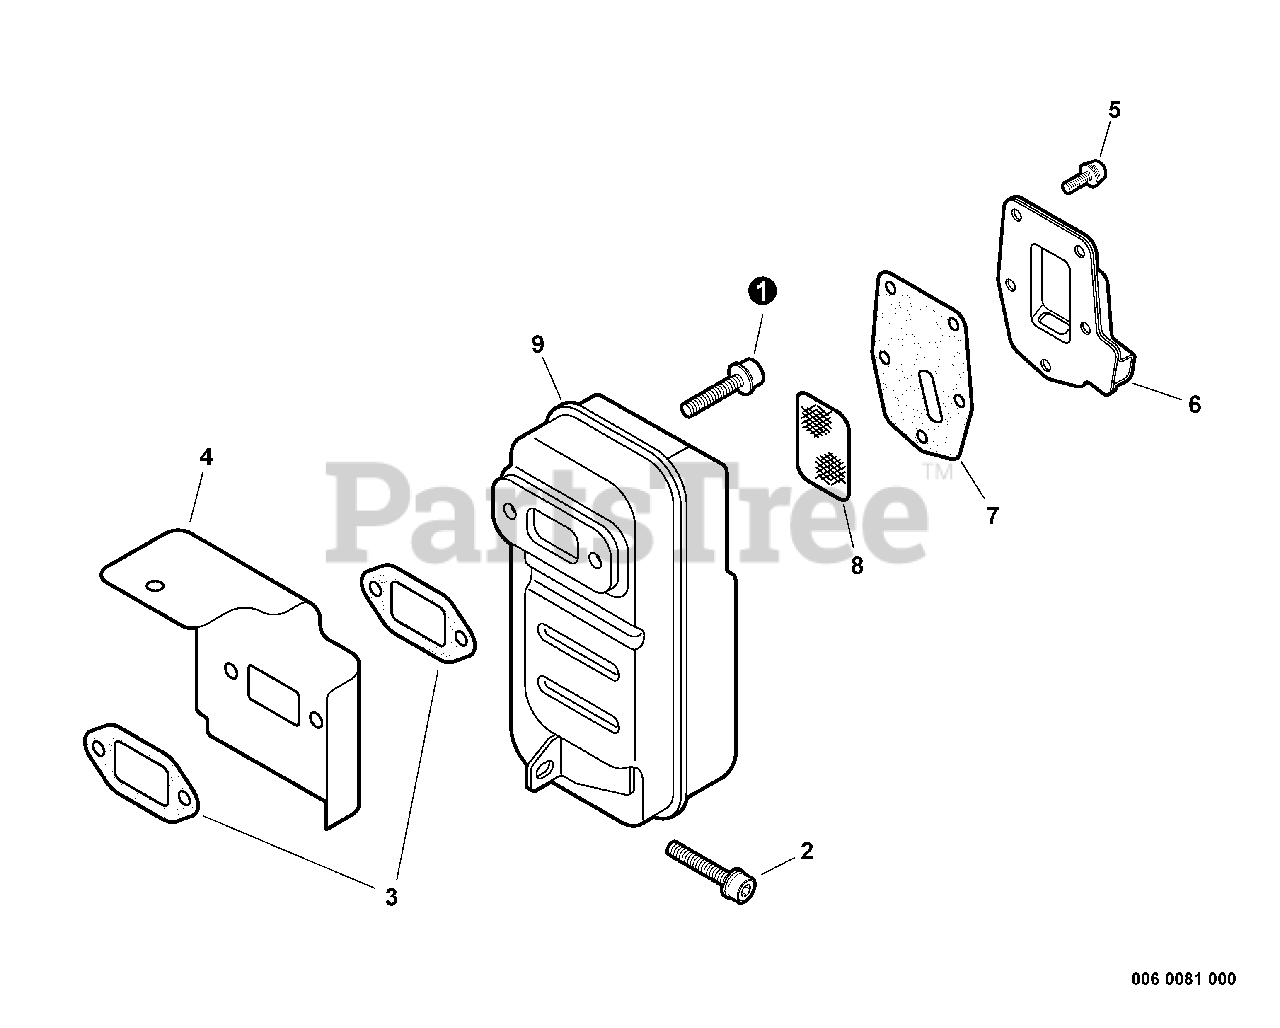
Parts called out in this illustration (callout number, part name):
1	SCREW - 6X20
2	SCREW - 5X20
3	GASKET, EXHAUST
4	SHIELD, CYLINDER - EXHAUST
5	SCREW - 4X10
6	GUIDE, EXHAUST
7	GASKET, EXHAUST
8	SCREEN, SPARK ARRESTOR
9	MUFFLER
